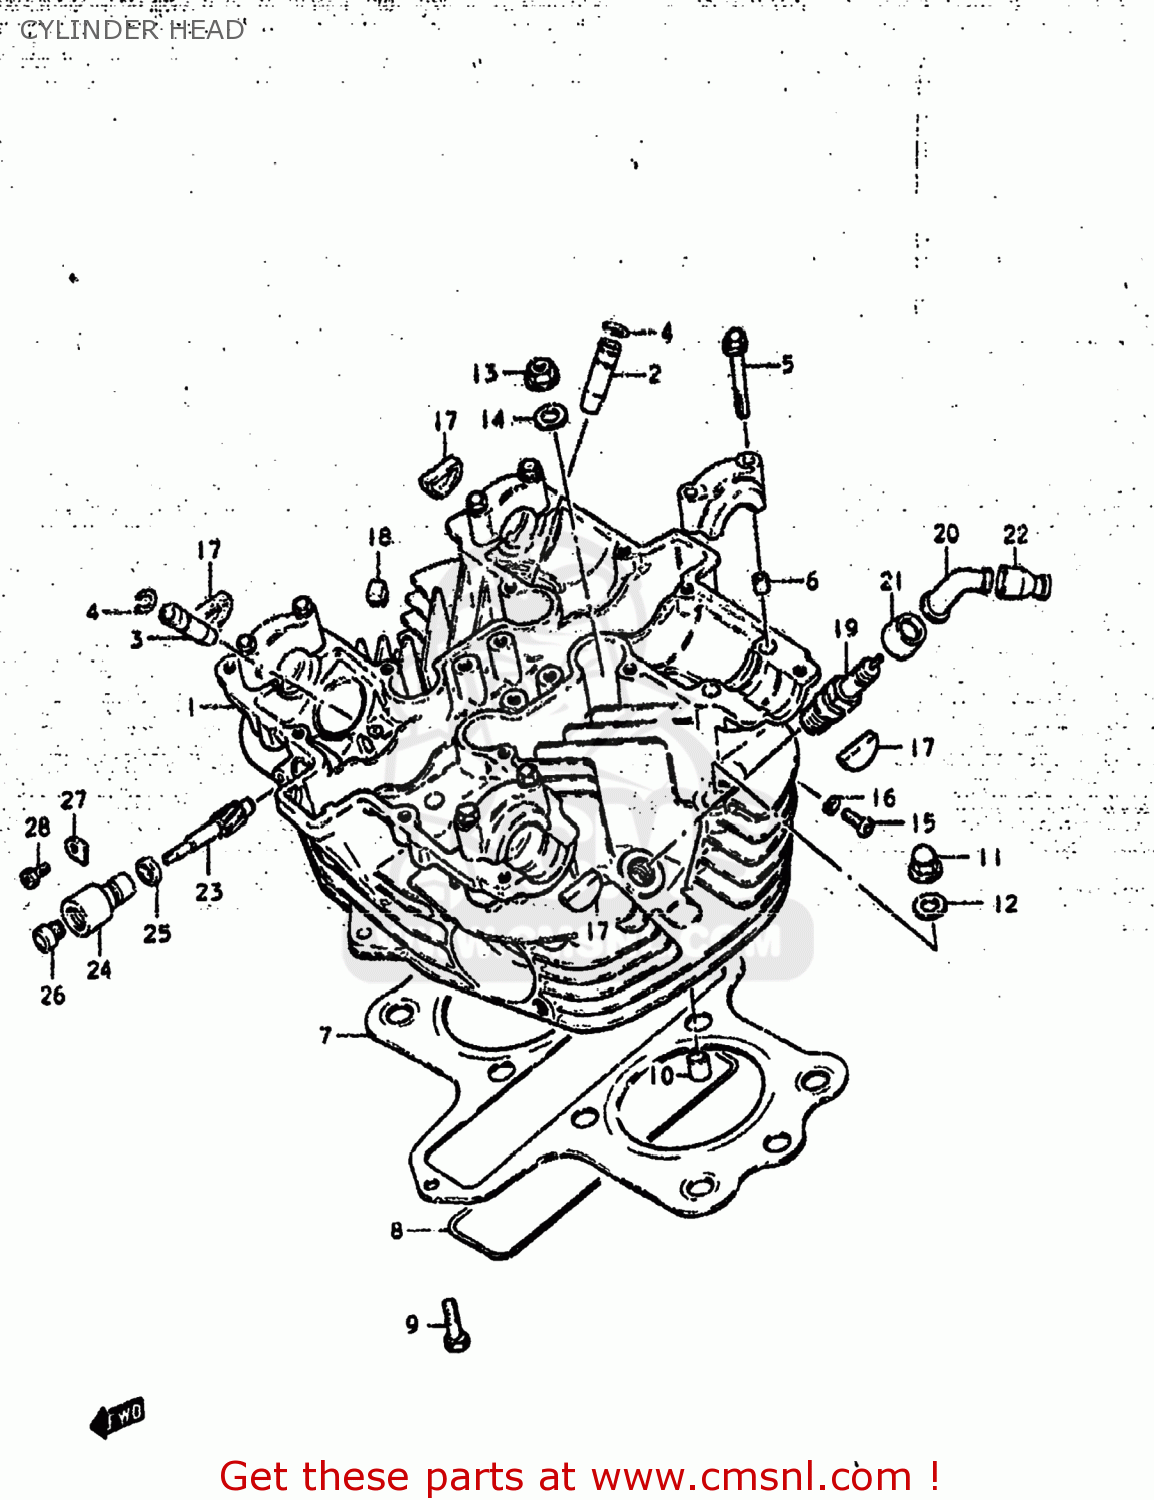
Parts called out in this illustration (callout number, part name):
1	HEAD SET,CYLINDER
2	GUIDE,INTAKE VALVE
3	GUIDE,EXHAUST VALVE
4	RING,SNAP
5	BOLT(6X39)
6	PIN(6.2X8X11)
7	GASKET,CYLINDER HEAD (MCA)
8	O RING(D:3,ID:26X157)
9	BOLT
10	PIN
11	NUT
12	GASKET(10.5X22X2) (NAS)
13	NUT
14	WASHER(10.5X22X2.3)
15	SCREW 5X20
16	GASKET(5.3X9.3X1.2) (NAS)
17	PLUG
18	PAD
19	PLUG,SPARK
20	CAP,SPARK PLUG
21	SEAL,SPARK PLUG
22	SEAL,SPARK PLU
23	GEAR,TACHOMETER DRIVEN
24	SLEEVE,TACHOMETER DRIVE
25	SEAL,TACHOMETER DRIVEN
26	OIL SEAL
27	PLATE,TACH DRIVE GEAR SLEEVE
28	SCREW(5X12)
